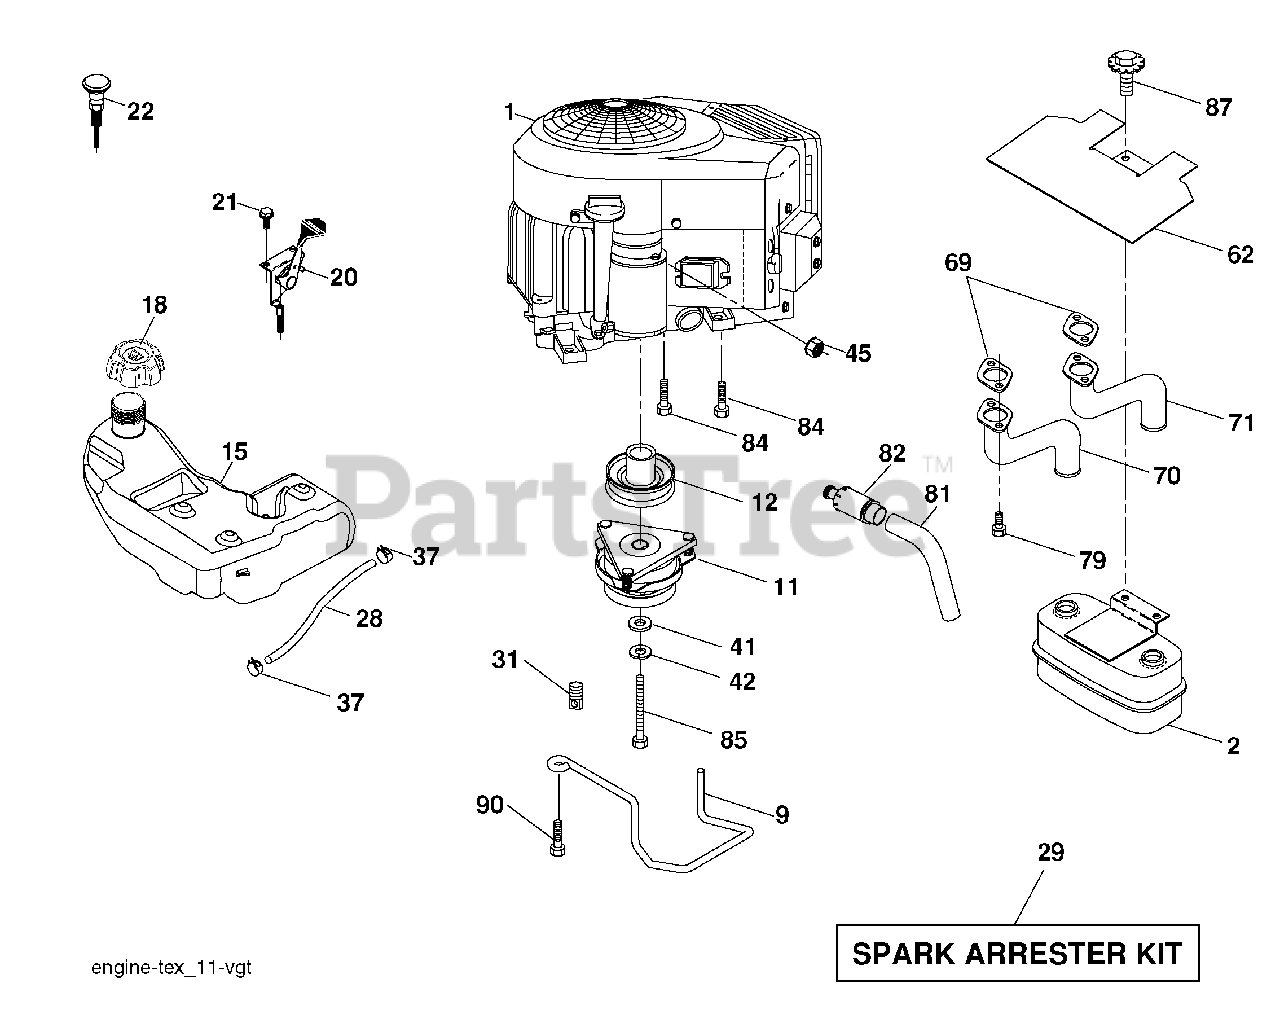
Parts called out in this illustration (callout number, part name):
2	Muffl er
9	Keeper Asm. Belt Engine
11	Clutch Electric
12	Pulley Engine
15	Tank Fuel 4.0
18	Cap Asm
20	Control Throttle
21	Screw 10 x 3/4 Single Lead-Hex
22	Control Choke
28	Fuel Line
29	Spark Arrester Kit
31	Clip Push-In Hinged
37	Clamp Hose
41	Washer 1-1/2 OD x 15/32 ID x .250
42	Washer Lock 7/16
45	Nut Keps Hex 1/4-20 unc
62	Shield Heat Muffl er
69	Gasket
70	Tube Exhaust LH
71	Tube Exhaust RH
79	Screw Socket Head
81	Tube Drain Oil Easy
82	Plug Drain Oil
84	Screw 3/8-16 x 1-1/4
85	Bolt Hex 7/16-20 x 3.75 Gr. 5
87	Bolt 5/16-18 unc x 1 w/Sems
90	Screw 3/8-16 x 1
